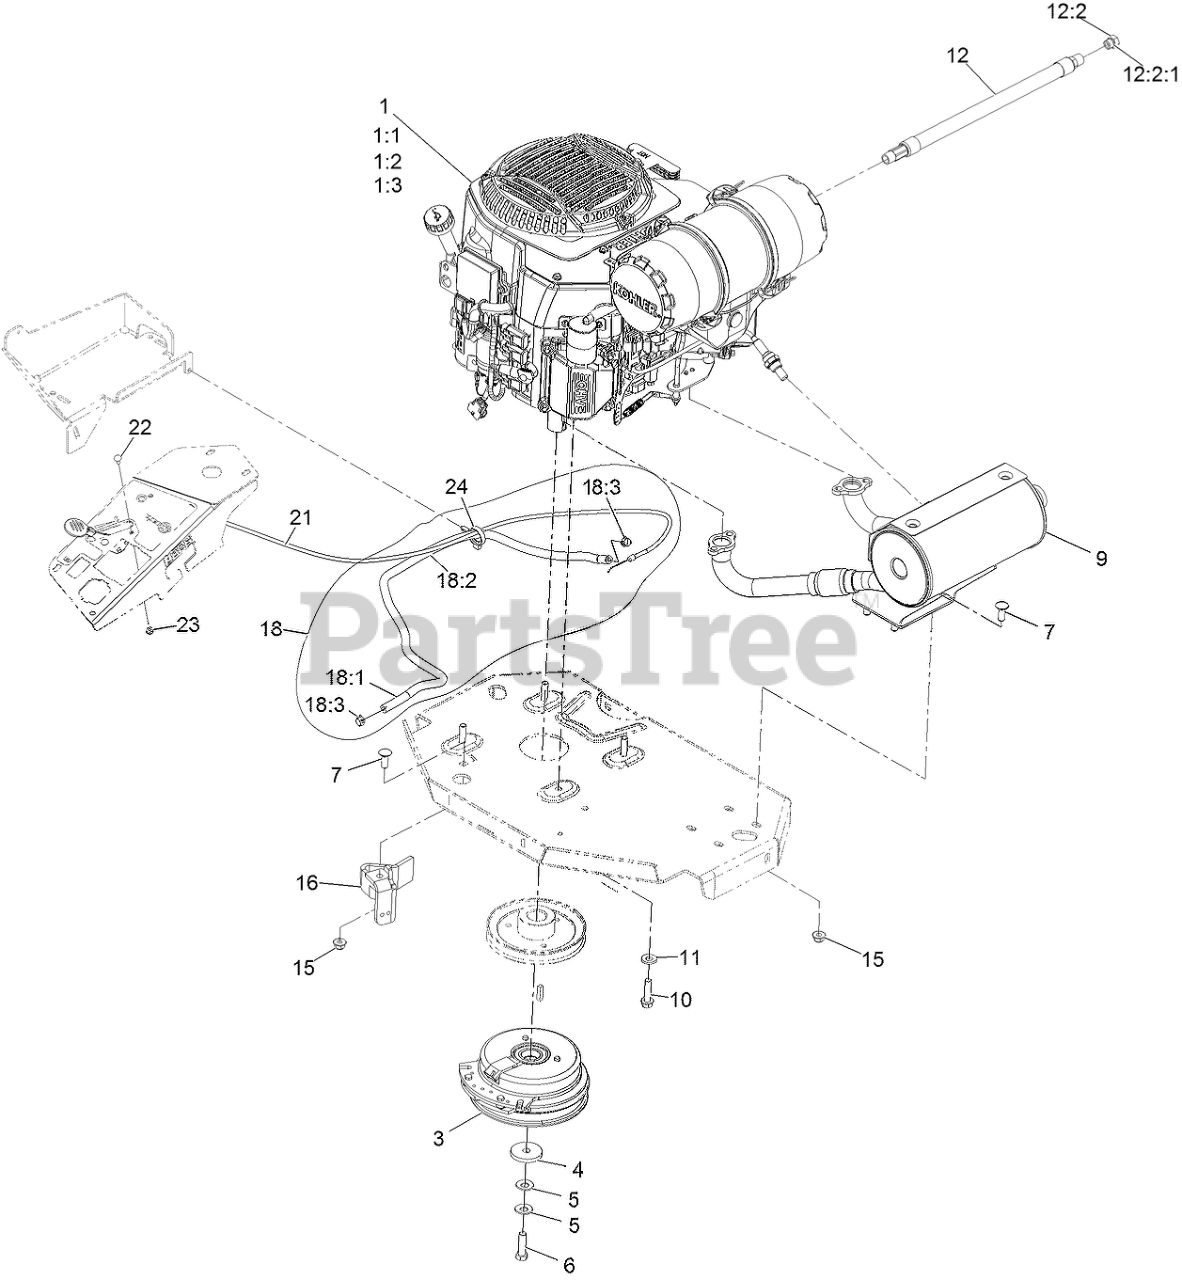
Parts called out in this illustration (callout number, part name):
1:1	Kohler 52 050 02-S Engine Oil Filter
1:2	Kohler 25 083 01-S Engine Air Filter
1:3	Kohler 25 083 04-S Safety Filter
3	CLUTCH KIT
4	WASHER-CLUTCH
5	WASHER-SPRING
6	SCREW-HH 7/16-20 X 1 1/2 W/LOCTITE
7	SCREW-CARR
9	KIT,MUFFLER
10	SCREW-HWH
11	WASHER-BELLEVILLE
12	OIL DRAIN HOSE ASM
12:2	PLUG-HH
12:2:1	O-RING
15	NUT-HF, NI
16	CLUTCH-ANCHOR
18	FUEL LINE ASM
18:1	HOSE-FUEL
18:2	SLEEVE-THERMAL
18:3	CLAMP-HOSE
21	ASM,THROTTLE CABLE
22	BOLT-CARR
23	NUT-LOCK, NI
24	CLAMP-HOSE
